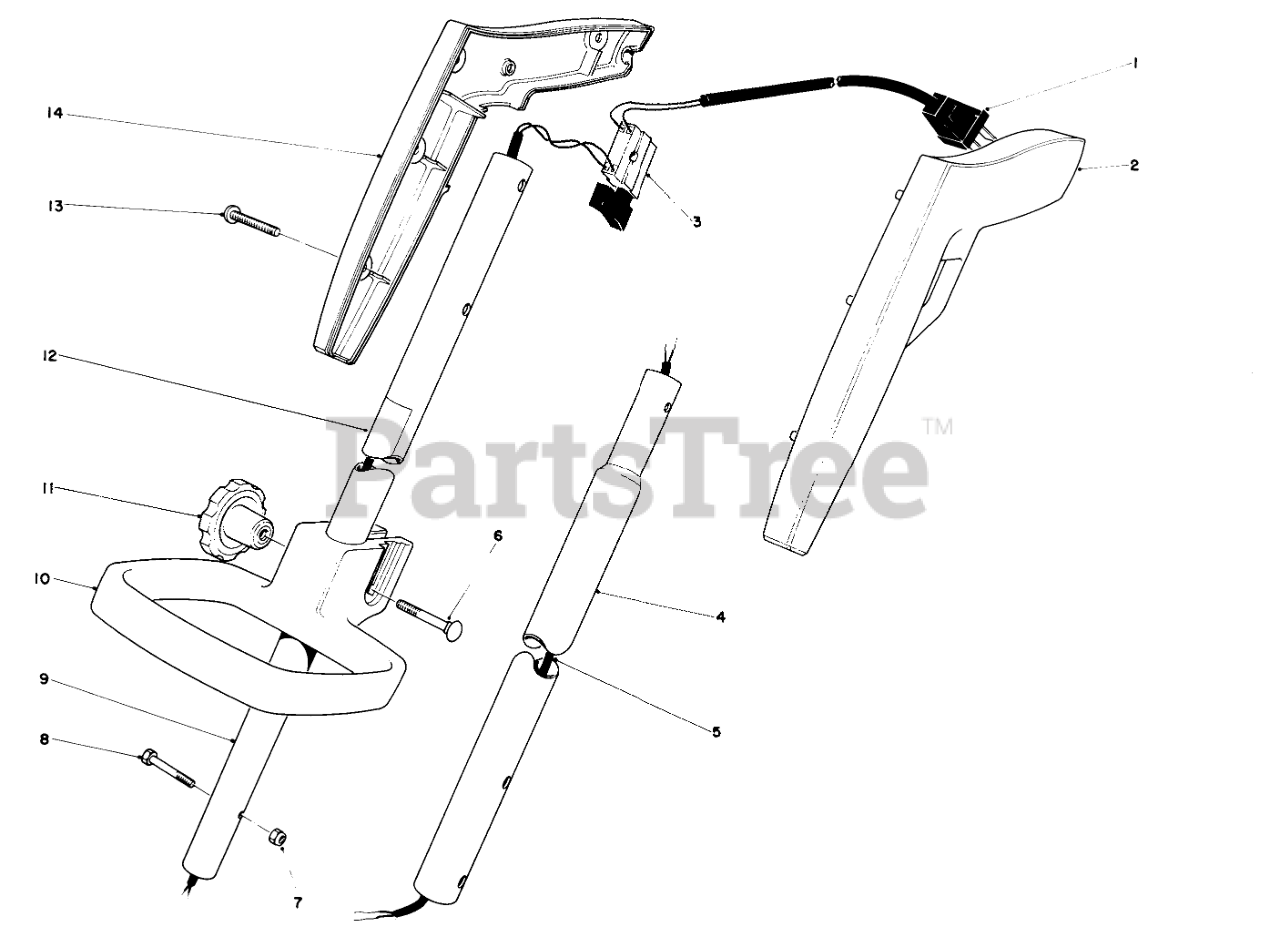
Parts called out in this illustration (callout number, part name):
1	Plug-Pigtail
2	Grip L.H.
3	SWITCH SINGLE SPEED
4	Tube-Lower
5	Wiring Harness
6	BOLT-CARR
7	NUT-LOCK, NI
8	HEX HD MACHINE SCREW
9	Tube-Upper
10	ADJUSTABLE HANDLE
12	Decal-Serial (Canada)
13	Screw
14	R.H. GRIP
